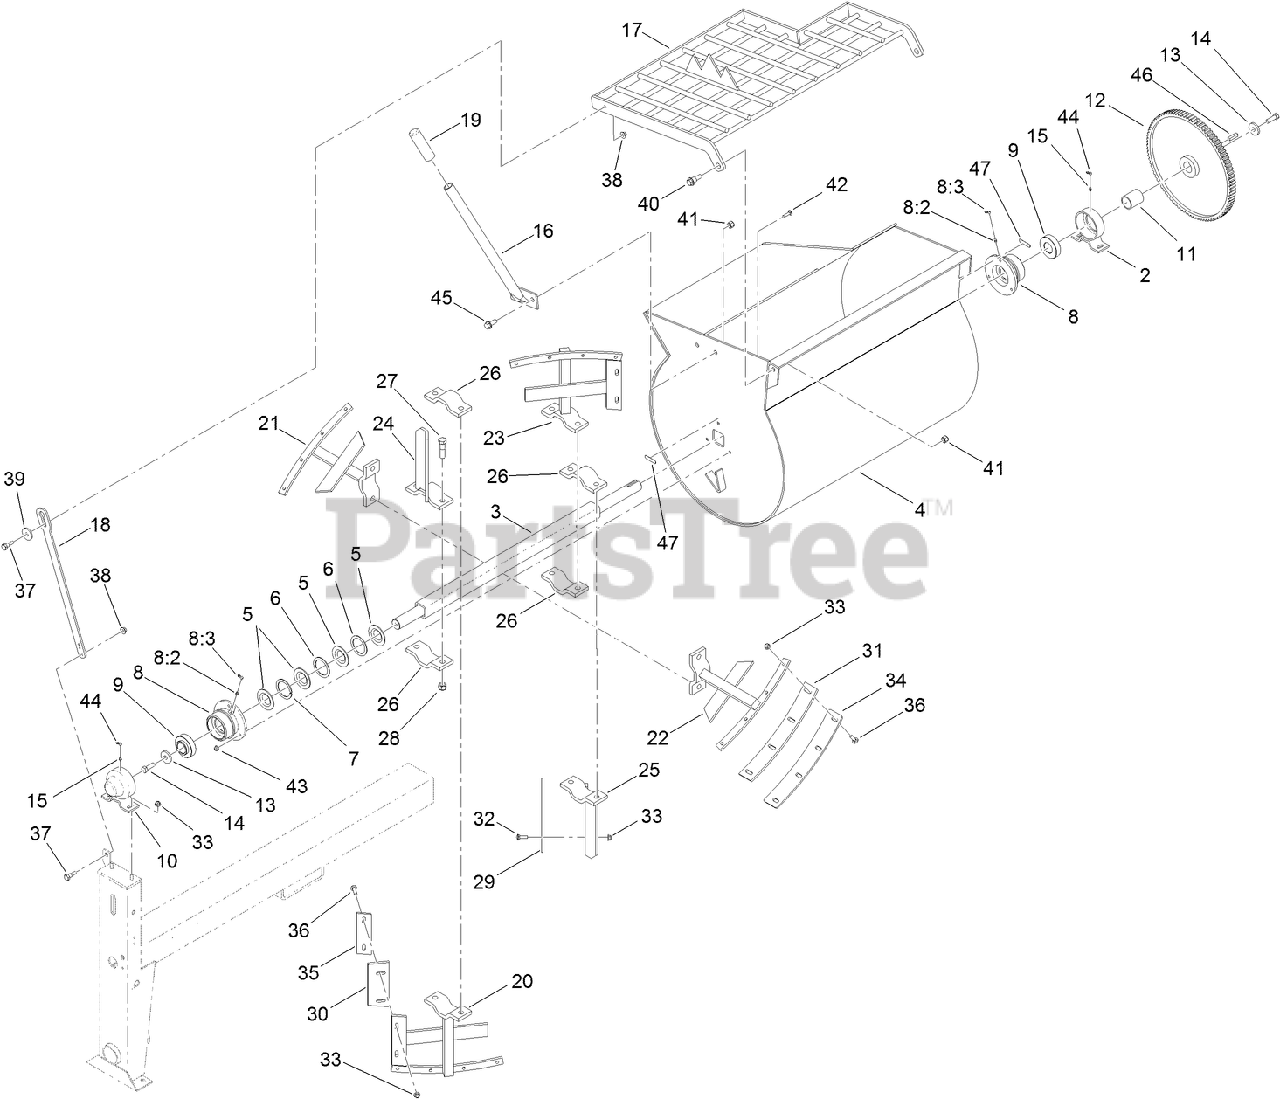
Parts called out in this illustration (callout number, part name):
2	TRUNNION
3	SHAFT-PADDLE
5	SEAL-DRUM
6	WASHER-FLAT
7	WASHER-SPLIT
8	KIT-HOUSING, BEARING
8:2	FITTING-GREASE
8:3	CAP-PLUG
9	BEARING-BALL
10	TRUNNION-CAPPED
11	SPACER-SHAFT, DRUM
12	GEAR-94 TEETH
13	WASHER-FLAT
14	SCREW-HH
15	FITTING-GREASE
16	HANDLE-DUMP
17	GUARD-DRUM
18	GUARD-LIFTER
19	GRIP-HAND
20	PADDLE-FRONT
21	PADDLE-MID
22	PADDLE-MID
23	PADDLE-REAR
24	PADDLE-PUSHER
25	PADDLE-PUSHER
26	CLAMP-PADDLE
27	SCREW-HH
28	NUT-LOCK, NI
29	BAR-BACKER, PUSHER END
30	BLADE-RUBBER, MIXER END
31	BLADE-RUBBER, MIXER TOP
32	BOLT-CARR
33	NUT-HF, NI
34	BAR-BACKER, TOP
35	BAR-BACKER, END
36	SCREW-CARR
37	BOLT-SHOULDER
38	NUT-FLANGE
39	Washer-Thrust
40	SCREW-SHOULDER, HHF
41	NUT-LOCK, NI
42	SCREW-CARR
43	NUT-HF, NI
44	CAP-PLUG
45	SCREW-HHF
46	KEY-SQUARE
47	DECAL-GREASE
